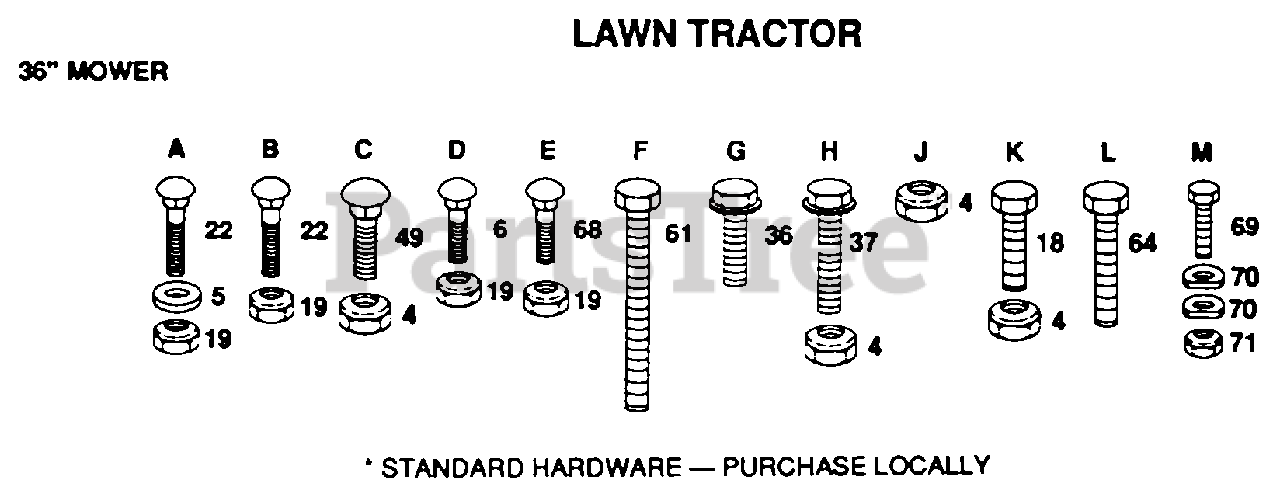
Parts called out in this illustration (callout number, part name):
5	WASHER M
6	BOLT
22	BOLT
36	SCREW
37	SCREW
49	BOLT
61	BOLT
64	BOLT.3/8-14X1.25
69	BOLT LT
70	WASHER T
